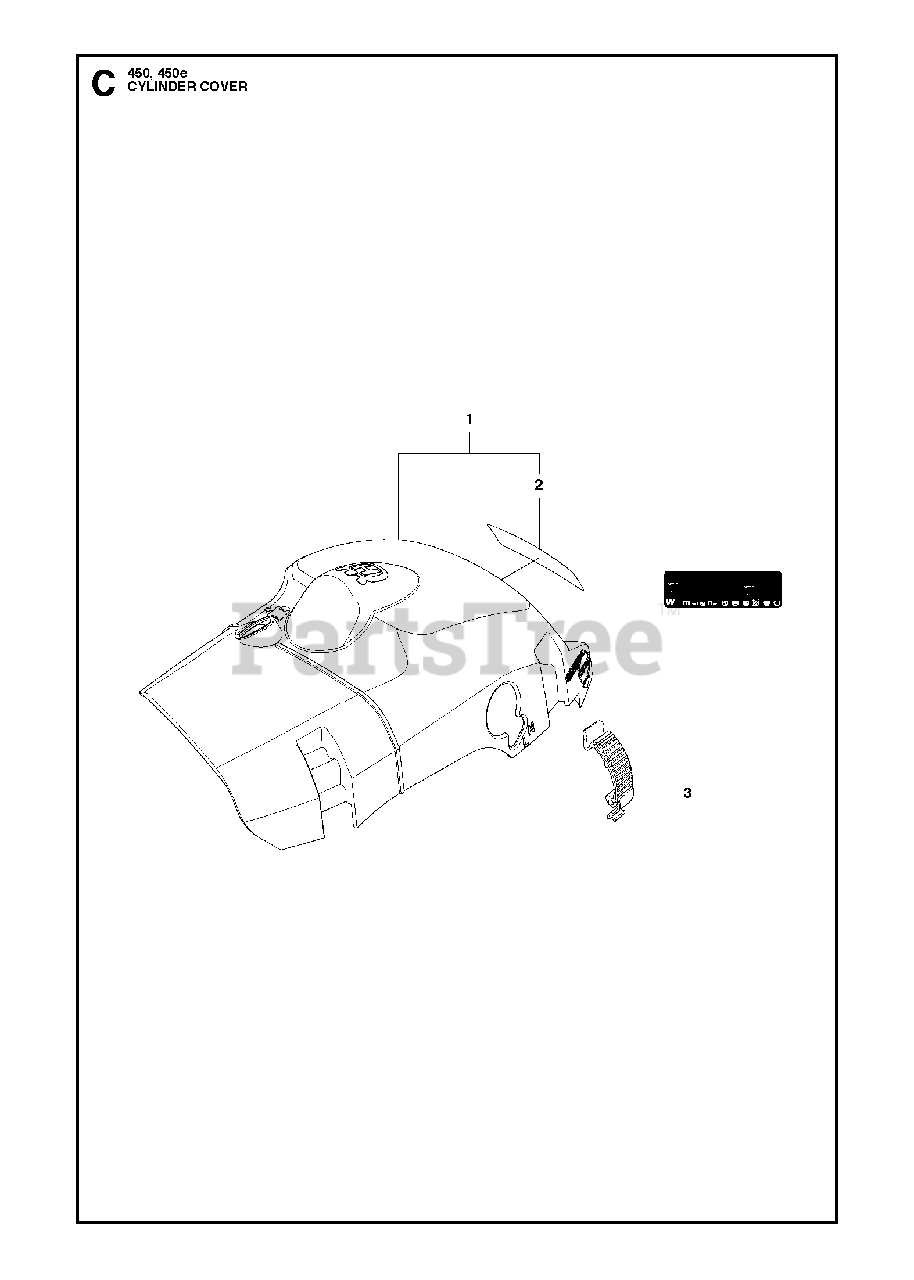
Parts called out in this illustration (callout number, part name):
1	CYLINDER COVER ASSY
2	LABEL
3	BUCKLE ORANGE
